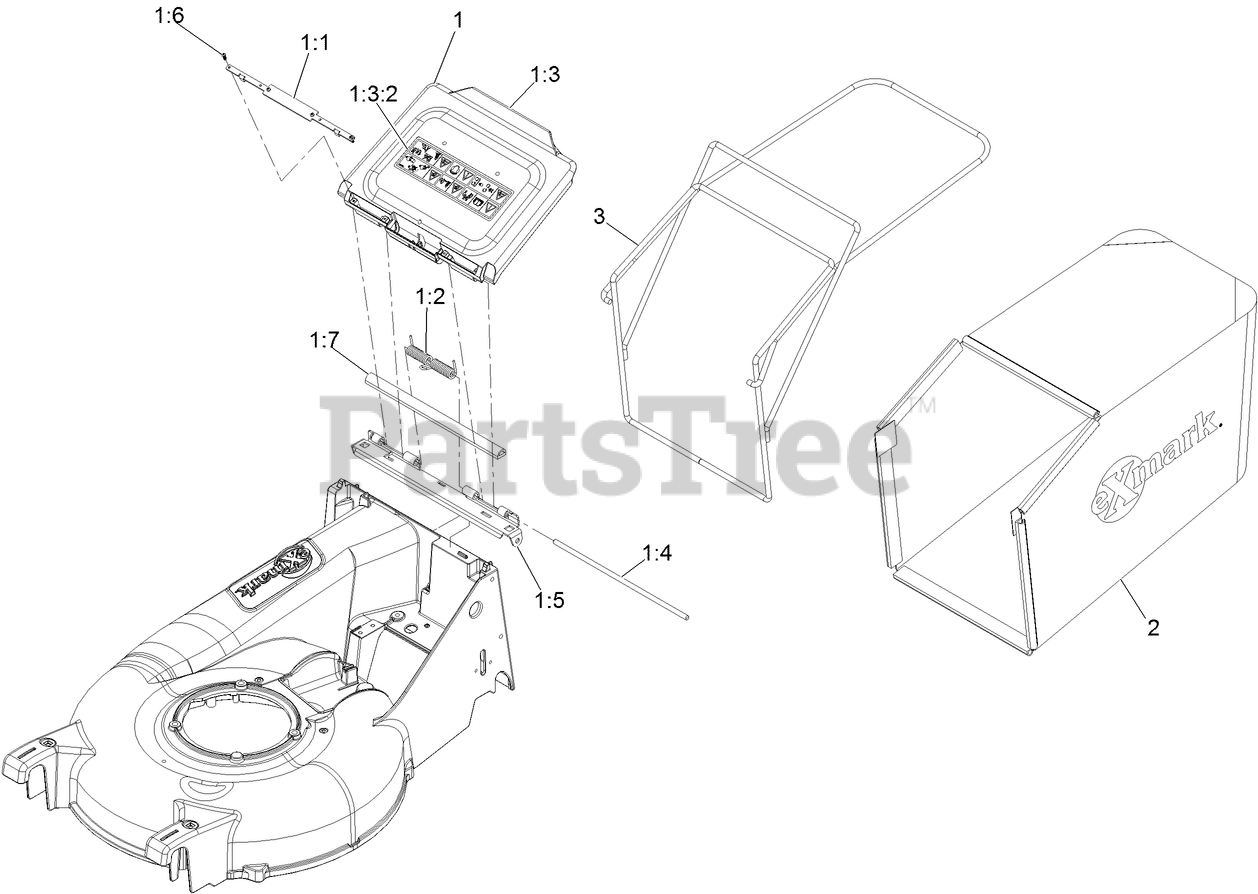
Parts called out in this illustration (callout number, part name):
1	DOOR ASM
1:1	X-REF 126-2628-03
1:2	SPRING-PLASTIC DOOR
1:3	ASM-DOOR & DECAL
1:3:2	DECAL-WARNING
1:4	PIN-DOOR PIVOT
1:5	X-REF TO 126-2636-03
1:6	SCR,TAP,6-19X7/16,PHPH, S
1:7	SEAL-EPDM FOAM BULB
2	BAG-GRASS EC21
3	WLD-BAG FRAME
